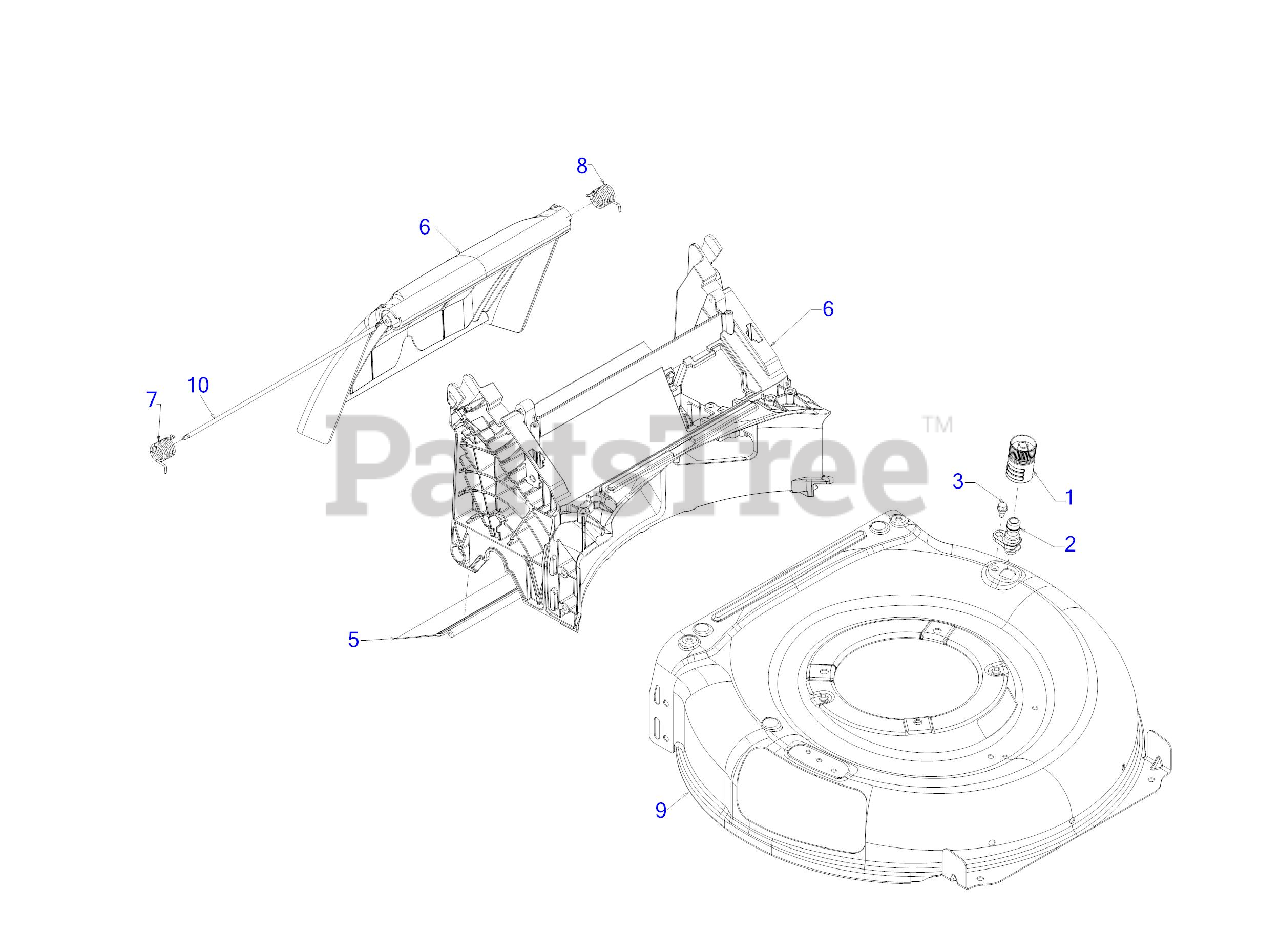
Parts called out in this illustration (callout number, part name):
1	WATER NOZZLE
2	DECK WASH NOZZLE
3	SHOULDER SCREW 1/4-20 x .50
4	MULCH PLUG
5	TRAILSHIELD
6	REAR BAFFLE ASSEMBLY
7	TORSION SPRING (RH)
8	TORSION SPRING (LH)
10	REAR DOOR PIVOT ROD
